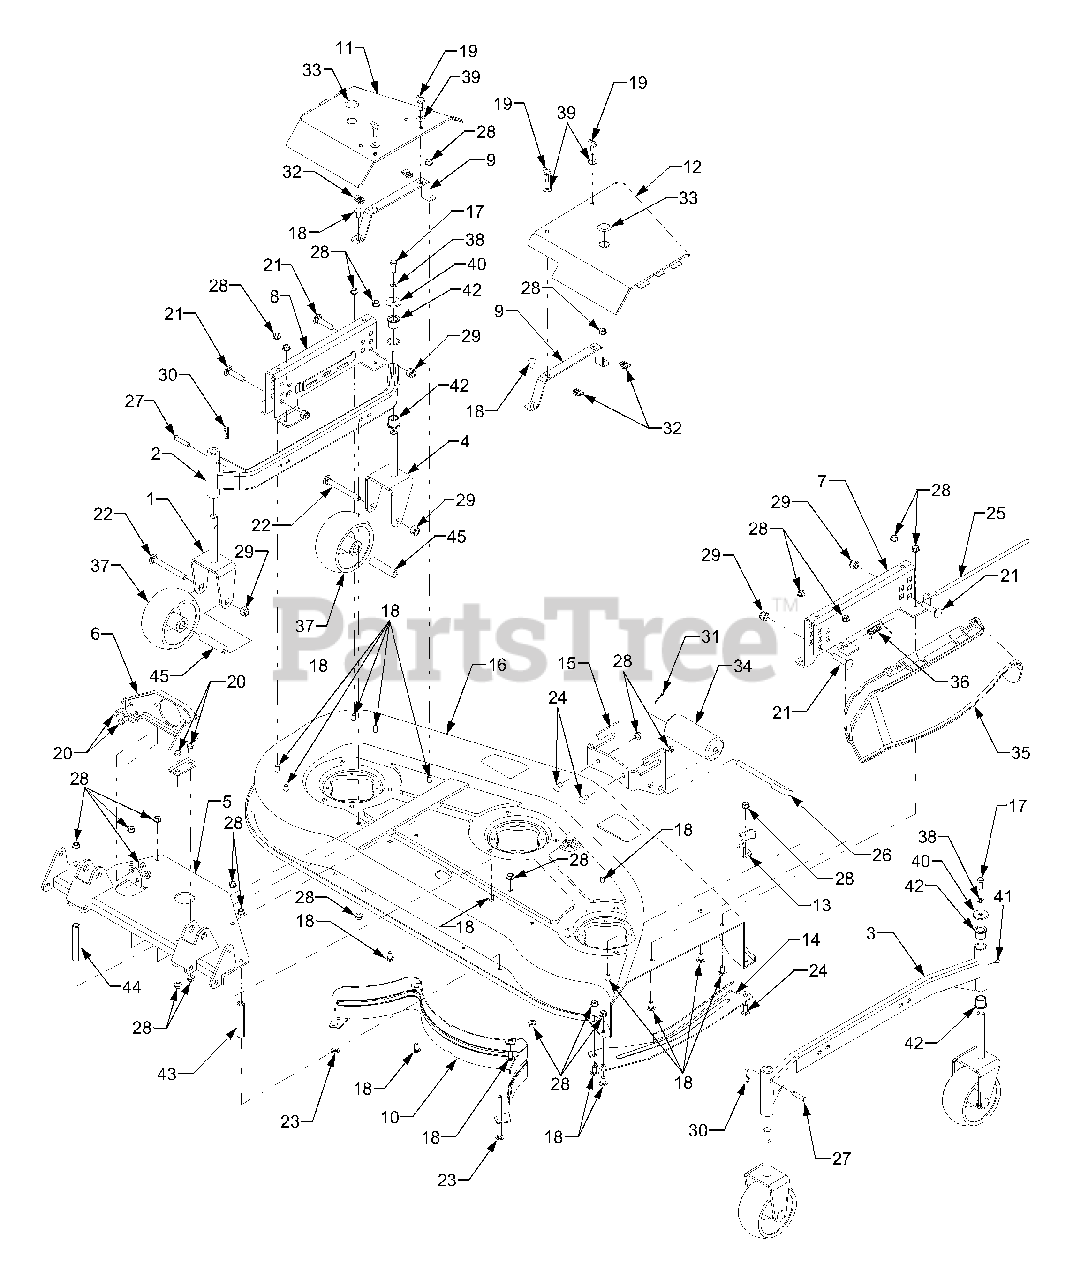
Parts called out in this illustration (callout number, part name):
1	Wheel Yoke, Rear
2	Axle, Caster, LH
3	Axle, Caster, RH
4	Wheel Yoke, Front
5	Plate Assembly, Mounting
6	Bracket, Gear Box
7	Bracket, Caster Mounting RH
8	Bracket, Caster Mounting RH
9	Strap, Mounting
10	Baffle, Rear Inner
11	Cover, Belt (L.H.)
12	Cover, Belt (R.H.)
13	Stop, Chute Deflector
14	Guard, Finger
15	Bracket, Front Roller
17	Screw, Hex Cap 3/8-16 x 1.0 GR5
18	Carriage, Bolt 3/8-16 x .75
19	Screw, Thumb Adjust 5/16-18 x 1
20	Screw, Hex Cap 3/8-16 x .75 GR5
21	Screw, Carriage 1/2-13 x 2.125 GR5
22	Screw, Carriage 1/2-13 x 4.5 GR5
23	Carriage, Bolt 3/8-16 x 5.0 GR5
24	Carriage, Bolt 3/8-16 x 1.0
25	Pin, Hinged .375 x 14.06
26	Pin, Roller 1/2 x 7.31
27	Pin, Clevis, 3/8 x 1.75
28	Nut, Flange Lock 3/8-16
29	Nut, Hex Nylon Lock 1/2-13 GR8
30	Pin, Internal Cotter
31	Pin, Cotter 3/32 x 1.25
32	Nut, "U" 5/16-18
33	Plug, Button
34	Roller, Front
35	Deflector, Chute
36	Spring, Torsion
37	Caster, Wheel w/Bearings
38	Washer, Lock 3/8" I.D.
39	Washer, Bell .34" I.D.
40	Washer, Flat, .39 x 1.5 x .134
41	Fitting, Lube
42	Bearing, Flange, .754 ID
43	Spacer, .405" I.D. x 3.875" Lg.
44	Spacer, .405' I.D. x 4.075" Lg.
45	Axle, Caster Wheel
